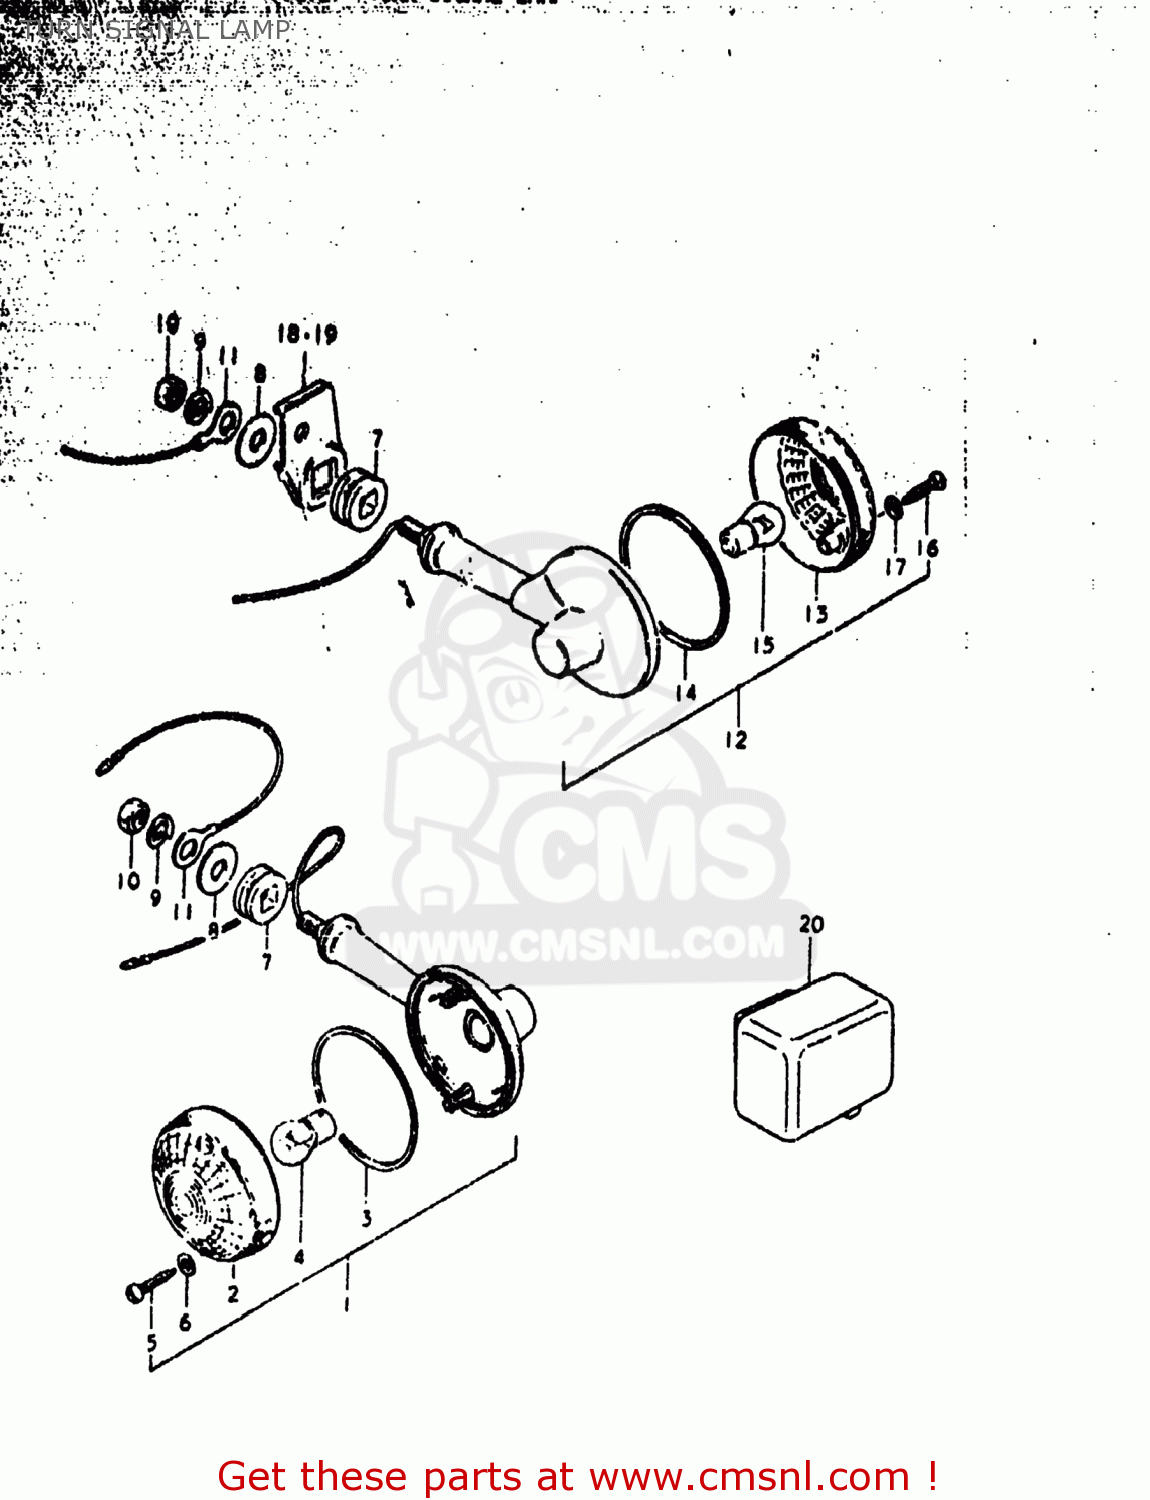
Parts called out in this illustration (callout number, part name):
1	LAMP ASSEMBLY,FRONT TURN SIGNAL
2	LENS
3	GASKET (NAS)
4	BULB(12V23W,STANLEY,A4577A)
5	BOLT
6	GASKET (NAS)
7	CUSHION
8	WASHER
9	LOCK WASHER
10	NUT
11	LEAD WIRE,EARTH
12	LAMP ASSEMBLY,FRONT TURN SIGNAL
13	LENS
14	GASKET (NAS)
15	BULB(12V23W,STANLEY,A4577A)
16	BOLT
17	GASKET (NAS)
18	BRACKET,RR TURNSIGNAL LAMP,R
19	BRACKET,RR TURNSIGNAL LAMP,L
20	RELAY,TURN SIGNAL
